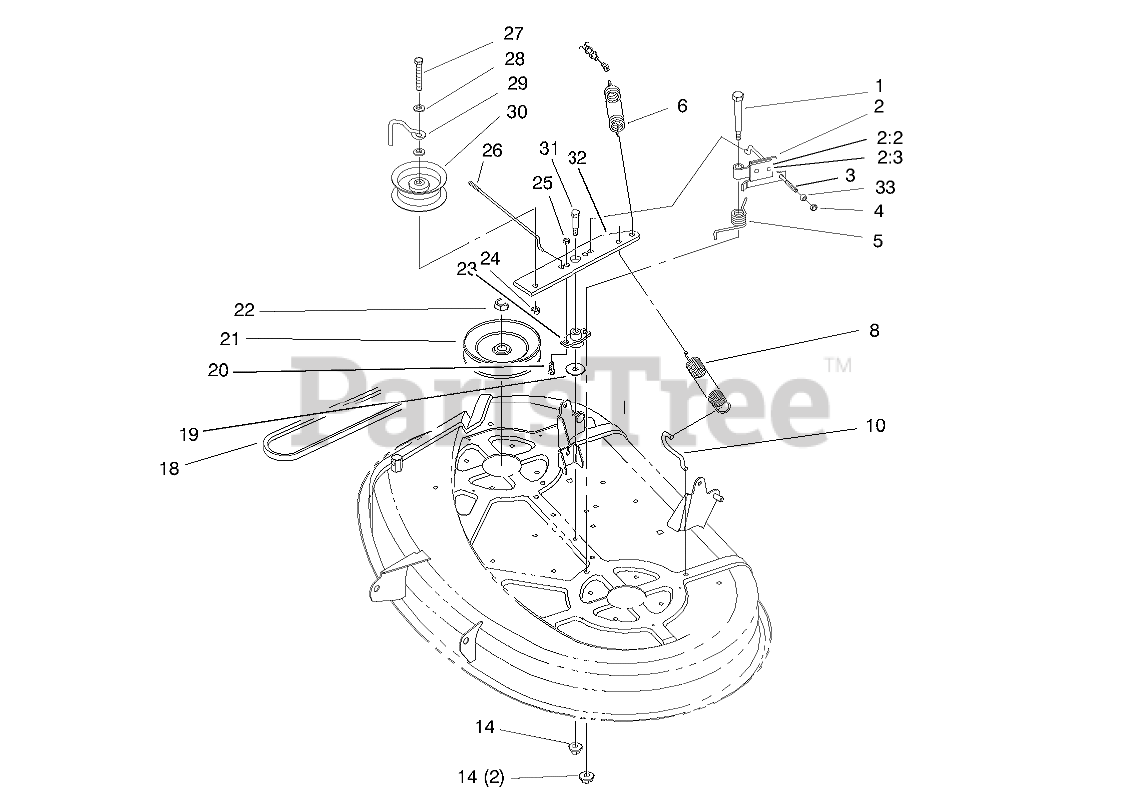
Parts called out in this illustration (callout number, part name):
1	BOLT-SHOULDER
2	BRAKE ASM
2:2	PAD-BRAKE
2:3	RIVET-BLIND
3	ROD-BRAKE, DECK LH
4	NUT-LOCK, NI
5	SPRING-TORSION
6	SPRING-DECK, ENGAGEMENT
8	SPRING-EXTENSION
10	HOOK-RETURN, SPRING
14	NUT-LOCK, NI
18	BELT-V
19	WASHER-FLAT
20	SCREW-HH
21	PULLEY
22	NUT-HEX
23	BUSHING-ARM, IDLER
24	NUT-LOCK, NI
25	NUT-LOCK, NI
26	ROD-BRAKE, DECK RH
27	SCREW-HH
28	WASHER-FLAT
29	GUIDE-IDLER, BELT
30	PULLEY-IDLER, FLAT
31	SCREW-SHOULDER, HH
32	ARM-IDLER
33	BALL-SWIVEL, STOP
